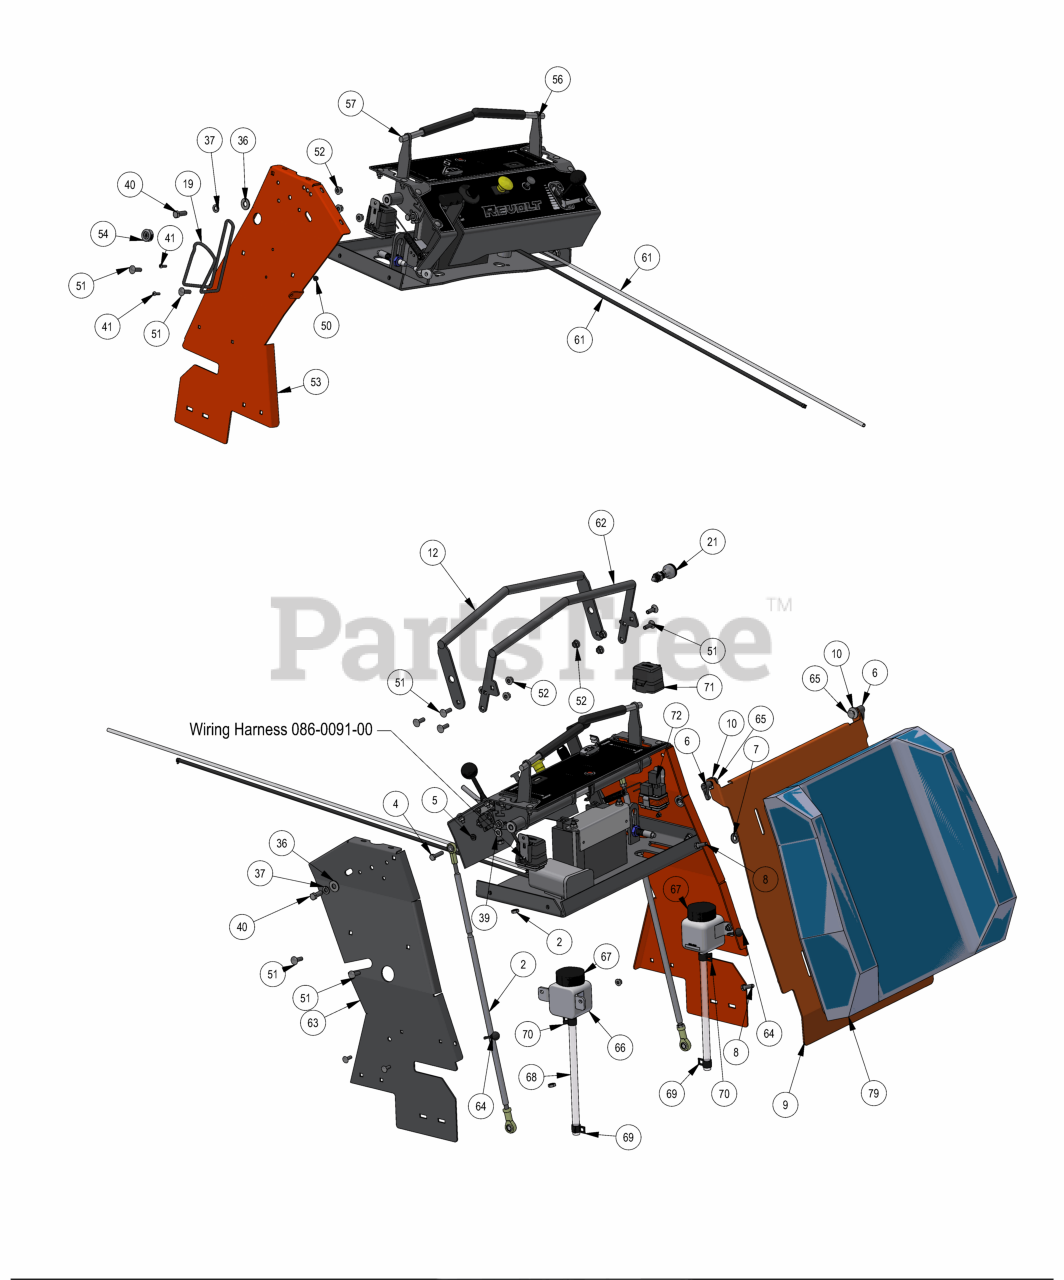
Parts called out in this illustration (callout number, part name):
1	Outlaw Throttle Cable
2	2019 Revolt Push Rod Assembly
3	ACS Spacer 3/4x3/8x1/4
4	5/16-18 X 1-1/4 HEX C/S (GR.5) ZC
5	5/16-18 NYLON INSERT JAM LOCKNUT ZINC
6	Adjustable handles ERX.30 B-10-24-C1
7	5/16 USS FLAT WASHER (7/8 OD) ZINC
8	5/16-18 X 1 HEX CAP SCREW (GR.5) ZINC
9	2023 Stand on Pad Plate
10	.360 ID X .983 OD X .120 THICK FLAT WASHER NYLON
11	2019 Stand On Brake Handle BLACK
12	Revolt Front Control Arm Stop Weldment BLACK
14	Safety Switch Harness
15	Tachometer
16	Ignition Switch
18	Magnet-Steering Arm-Stand ON
19	2019 Stand On Waterbottle Cage
20	2019 Stand On Control Grip
21	8507A13 McMaster Carr Plunger
22	Interstate FAYTX14 Battery
23	Brake Cable
24	PTO Switch
25	Universal Throttle Head - 2012
27	2019 Stand On Drive Arm Pivot Bar
28	8-32 HEX M/S NUT ZINC
29	Safety Switch
30	Rubber Brake Grip-cZT/ZT 2013
31	Throttle Knob
32	Brake Spring
33	Ignition Key
34	1/4-20 X 3/4 CARRIAGE BOLT (GR.5) ZINC
35	1/4-20 NYL INSERT FLANGE LOCKNUT ZINC
36	3/8 FLAT WASHER USS (1" OD) ZINC
37	3/8 SPLIT LOCKWASHER ZINC
38	.390 ID X 1.12 OD X .125 THK FLAT WASHER NYLON
39	.390 ID X .750 OD X .062 THK FLAT WASHER NYLON
40	3/8-16 X 1 GR 5 Hex Bolts Zinc
41	10-24 X 5/8 BUTTON SOCKET CAP SCREW 18-8 STAINLESS
42	3/8-16 X 1-1/4 CARRIAGE BOLT ZINC
43	5/16-18 X 1-1/2 CARRIAGE BOLT ZINC
44	12-24 X 1/2 HEX WASHER UNLSOT F TCS ZINC
45	5/16-18 X 6 CARRIAGE BOLT (GR.5) ZINC
46	M6-1.0 X 16MM DIN 933 HEX TAP BOLT (CL 8.8) ZINC
47	5/16-18 HEX SERRATED FLANGE NUT HARD/ZINC
48	3/8-24 HEX NUT ZINC YELLOW
49	3/8-16 NYLON INSERT FLANGE LOCKNUT (GR.F) ZINC
50	10-24 NYLON INSERT LOCKNUT ZINC
51	5/16-18 X 1 CARRIAGE BOLT (GR.8) ZINC
52	5/16-18 NYLON INSERT FLANGE LOCKNUT ZINC
53	2023 Podium Panel Right
54	Expandable Locking Grommets
55	Nylon 6 6 Sleeve Washer
56	2023 Stand On Drive Arm Actuator weldment_left
57	2023 Stand On Drive Arm Actuator weldment_right
58	2023 Stand On Podium Front Panel Weldment
59	2023 Stand on Battery Hold Down
60	2023 Stand On Console Bracket Weldment
61	MZ Kohler EPA Canister Assembly
62	2023 Control Arm Stop Weldment_Rear
63	2023 Podium Panel Left
64	2023 Floor Board Rubber Bumper
65	5/16-18 X 1-1/4 CARRIAGE BOLT ZINC
66	350ml Expansion Tank
67	Hydraulic Tank Cap
68	ZT/Maverick Hydro Tank Hose
69	3/8" Hose Clamp
70	1/2 Hose Clamp
71	Relay Block Cover Replacement Kit
73	Tachometer
74	48,54, & 61 Revolt Lower Control Panel Decal
75	48,54, & 61 Revolt Upper Control Panel Decal
76	Kawasaki \ Kohler Drive by Wire (Wescon R-Series)
77	36" Red Battery Cable
78	Ground Cable
79	2025 3-Piece Revolt Pad
